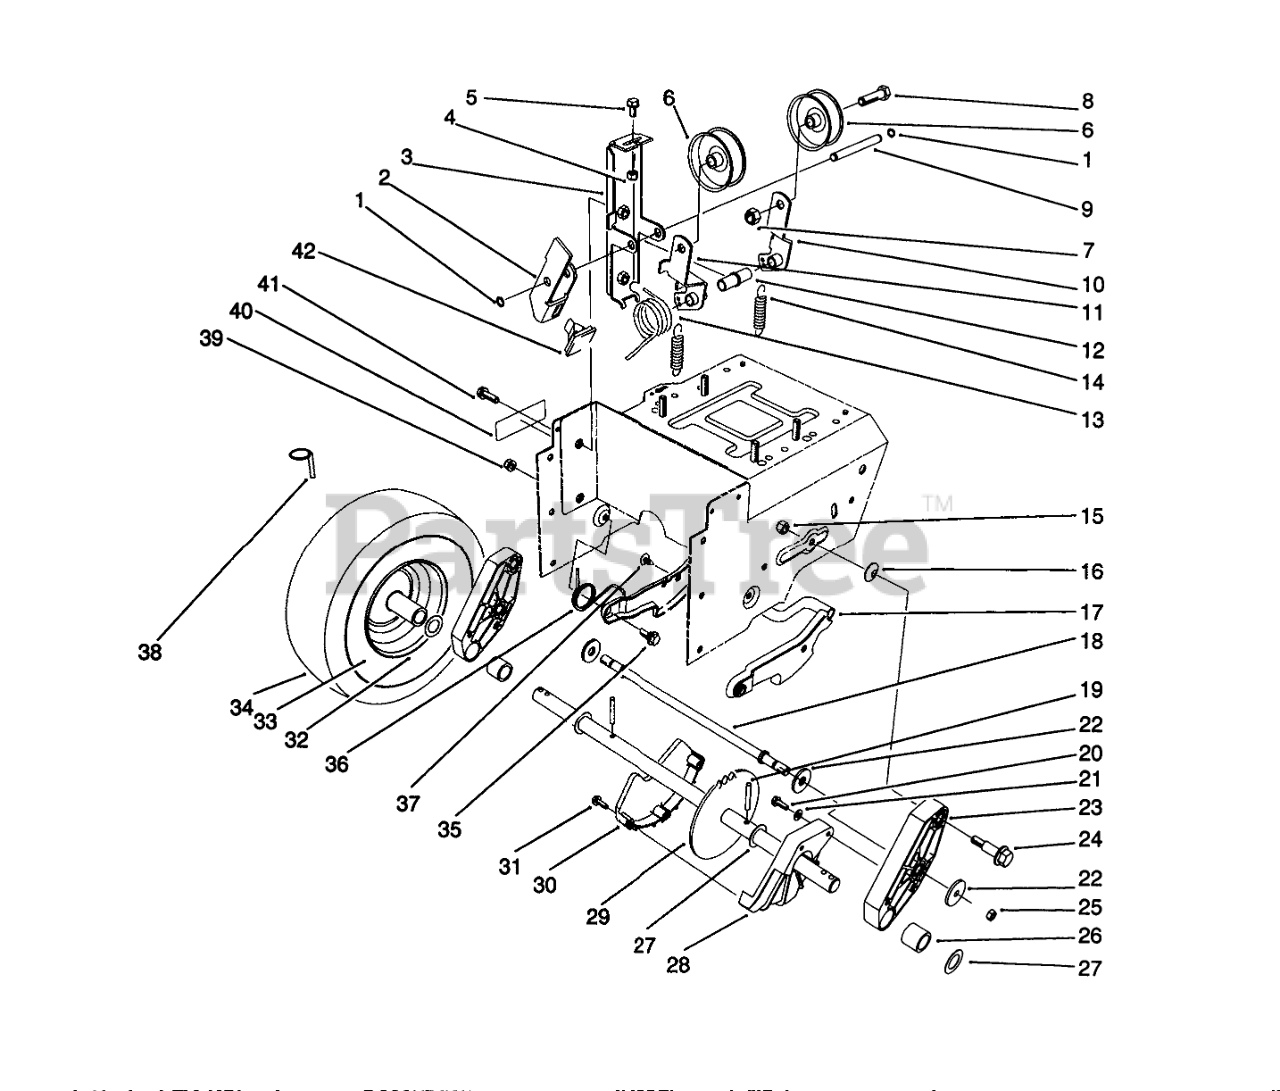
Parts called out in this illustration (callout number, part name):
1	RING-RETAINING
2	ARM-BRAKE
3	IDLER ARM BRACKET ASM
4	NUT-LOCK, NI
5	SCREW-HHF
6	Idler Pulley
7	NUT-LOCK, NI
8	SCREW-HH
9	PIN-IDLER
10	ARM-IDLER, TRACTION
11	ARM-IDLER, IMPELLER
12	BUSHING-IDLER
13	SPRING-TORSION
14	SPRING-EXTENSION
15	NUT-LOCK, NI
16	WASHER-SPRING
17	Latch-Arm
18	ROD-LATCH
19	PIN-ROLL, SLOTTED
20	SCREW-HWH
21	WASHER-FLAT
22	WASHER-SUPPORT
23	Pivot Arm Assembly (Incl. Ref. #26)
24	BOLT-SHOULDER
25	NUT-LOCK, NI
26	BUSHING-AXLE
27	WASHER-THRUST
28	GUARD-CHAIN, LH
29	AXLE ASM
30	GUARD-CHAIN, RH
31	Screw
32	WHEEL
33	TUBE-INNER
35	SCREW-SHOULDER
36	SPRING-LATCH, TORSION
37	FASTENER-PANEL
38	PIN-LYNCH
39	NUT-LOCK, NI
40	DECAL-WARNING
41	SCREW-HHF
42	PAD-BRAKE
